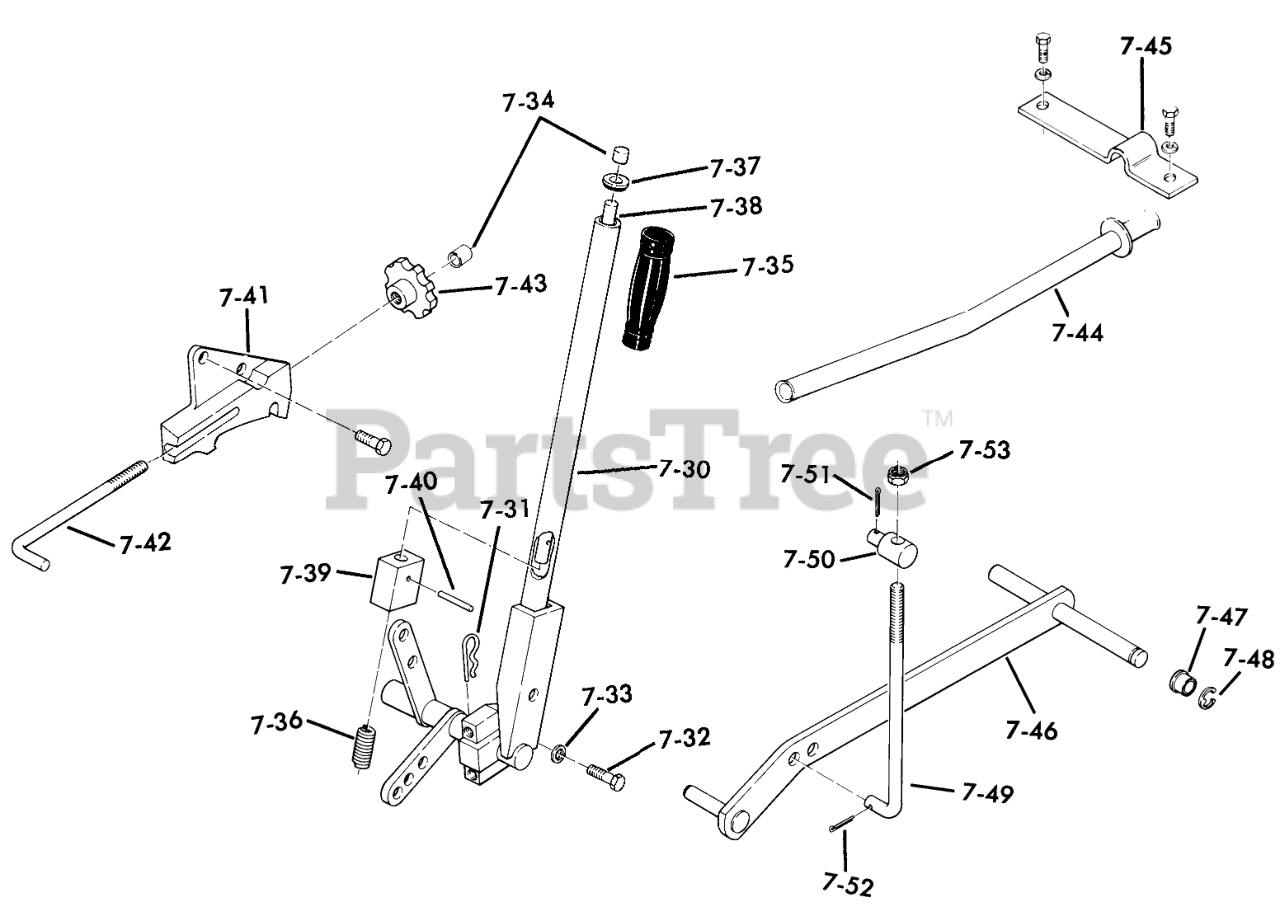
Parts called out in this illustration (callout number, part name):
7-30	Lift Lever
7-31	Hairpin
7-32	H H C S
7-33	Lockwasher
7-34	CAP-ROD, PLUNGER
7-35	HANDGRIP
7-36	SPRING-COMPRESSION
7-37	Guide-Rod
7-38	PLUNGER ROD
7-39	LOWER PLUNGER R
7-40	Roll Pin
7-41	Quadrant
7-41	Bolt
7-42	ROD-LIFT CONTROL
7-43	KNOB-LIFT CONTROL
7-44	Clamp-Conduit
7-45	Clamp-Tube
7-46	ASSY LIFT BAR R
7-47	BUSHING
7-48	E Ring
7-49	ROD-LIFT
7-50	TRUNNION-LIFT
7-51	Hairpin
7-52	Cotter Pin
7-53	NUT
